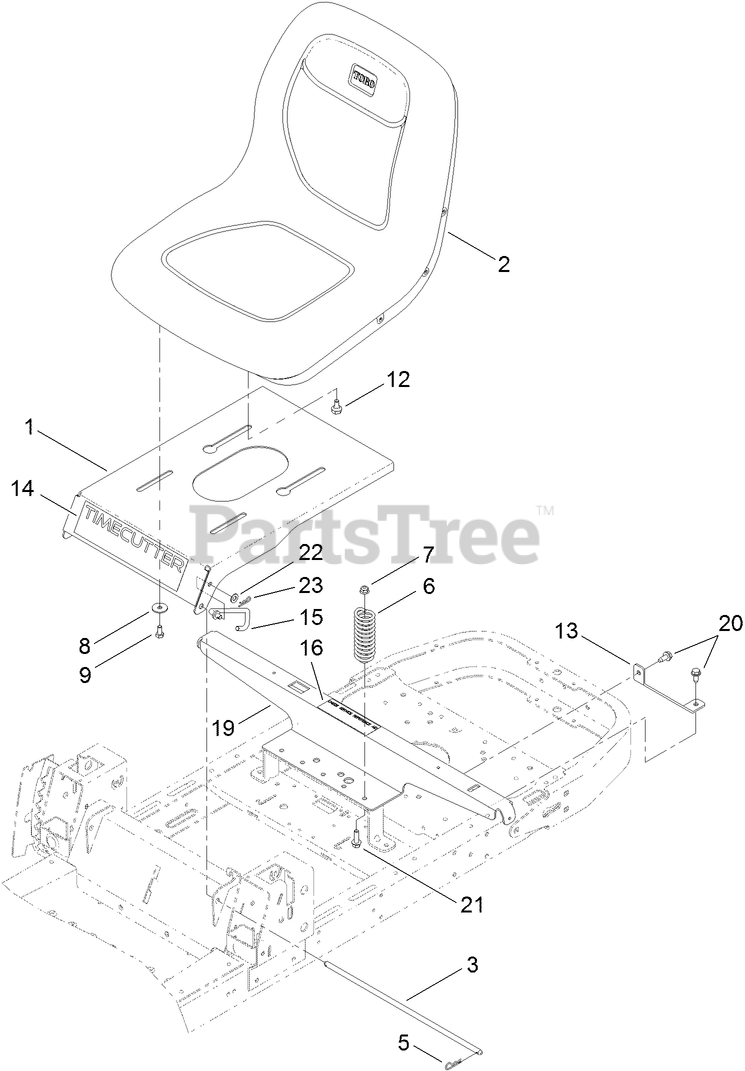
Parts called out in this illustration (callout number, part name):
2	SEAT-18 INCH
3	ROD-PIVOT, NARROW
5	PIN-COTTER
6	SPRING-COMPRESSION
7	NUT-HF, NI
8	WASHER-PIVOT
9	SCREW-HH
12	BOLT-SHOULDER,HFH
13	SUPPORT-TANK, REAR
14	DECAL-TIMECUTTER
15	STOP-SEAT
16	DECAL-SERVICE, CE
19	SUPPORT-POD
20	SCREW-HWHTF
21	SCREW-HHF
22	WASHER-PLAIN
